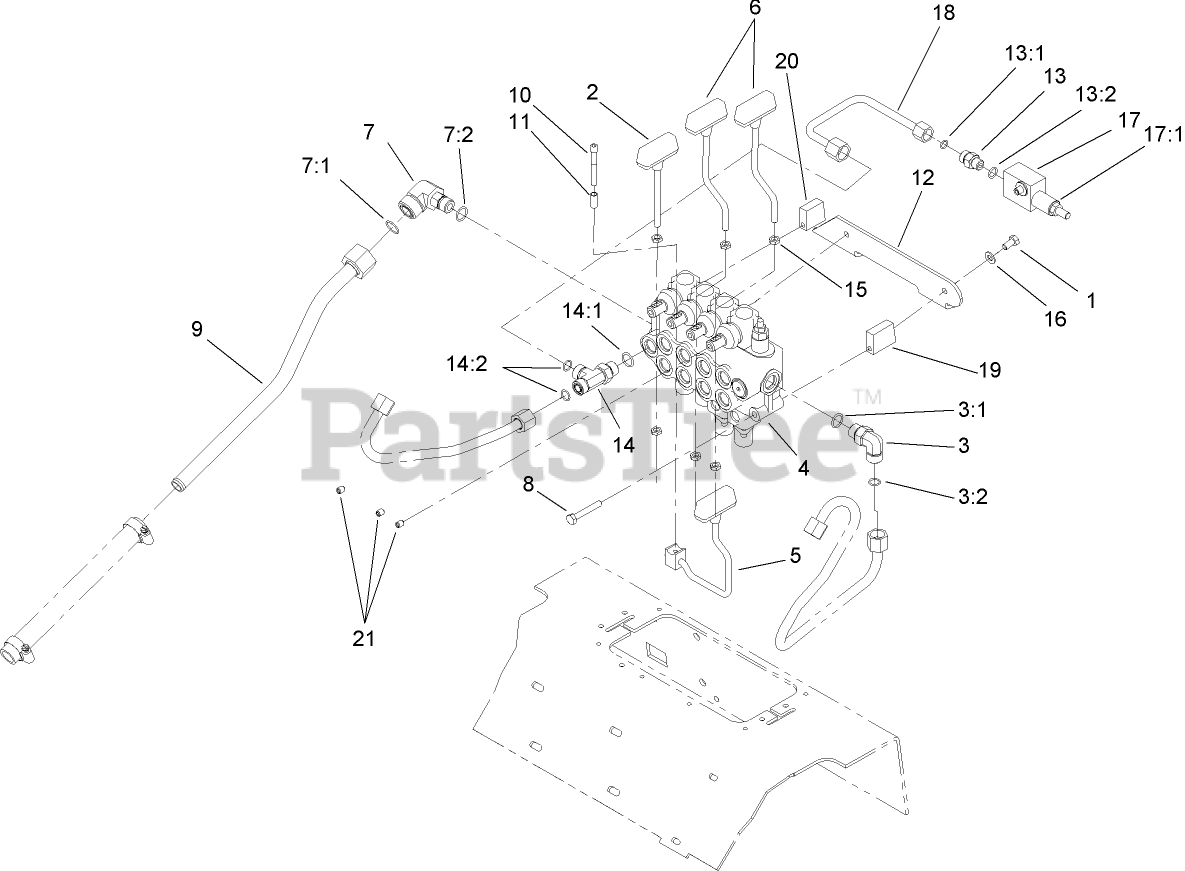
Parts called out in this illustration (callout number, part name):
1	SCREW-HH
2	LEVER-CYLINDER
3	FITTING-ELBOW-90 DEG
3:1	O-RING
3:2	O-RING
4	HYD FOUR SPOOL VALVE ASM
5	LEVER-CONTROL
6	LEVER-DRIVE
7	FITTING-HYD, 90 DEG
7:1	O-RING
7:2	O-RING
8	SCREW-HH
9	TUBE-TANK, HYD
10	SCREW-HSH
11	SPACER
12	BRACKET-COVER, MOUNT
13	FITTING-STRAIGHT
13:1	O-RING
13:2	O-RING
14	FITTING-TEE
14:1	O-RING
14:2	O-RING
15	NUT-HEX
16	WASHER-PLAIN
17	RELIEF VALVE ASM
17:1	CARTRIDGE-VALVE, RELIEF
18	LINE-HYD
19	SPACER-LOWER
20	SPACER-UPPER
21	SCREW-SET, HSH
